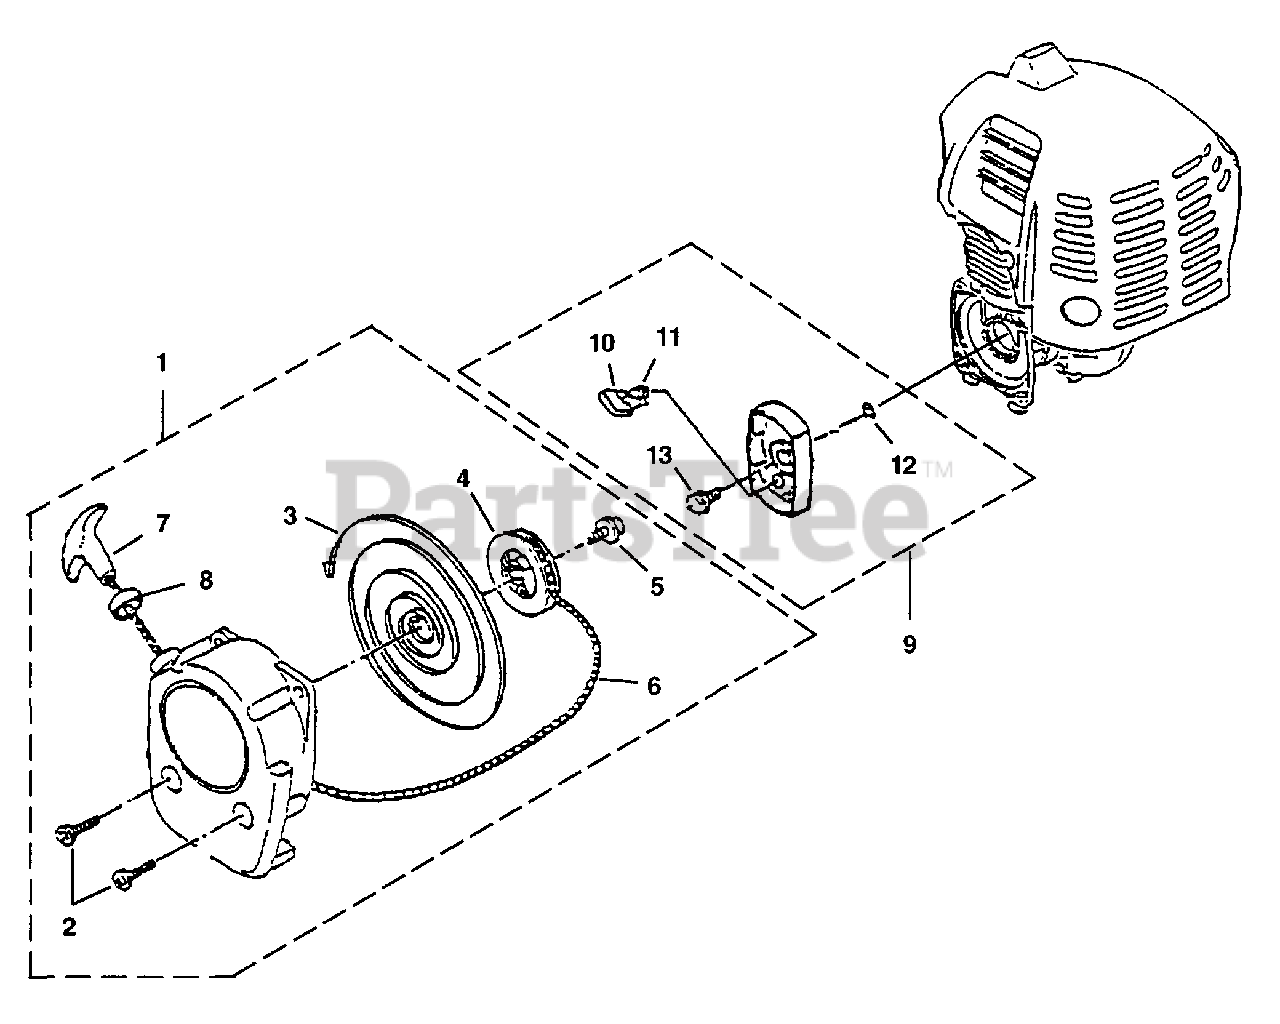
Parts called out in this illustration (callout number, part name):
1	STARTER COMPLETE
2	SCREW - Socket Hd (M5 x 30)
5	SCREW - Set (M5 x 30)
6	ROPE - Starter
8	DAMPER - Grip
9	STARTER CUP ASSEMBLY
11	SPRING - Return
12	E - CLIP
13	BOLT ASSEMBLY (M6 x 16)
